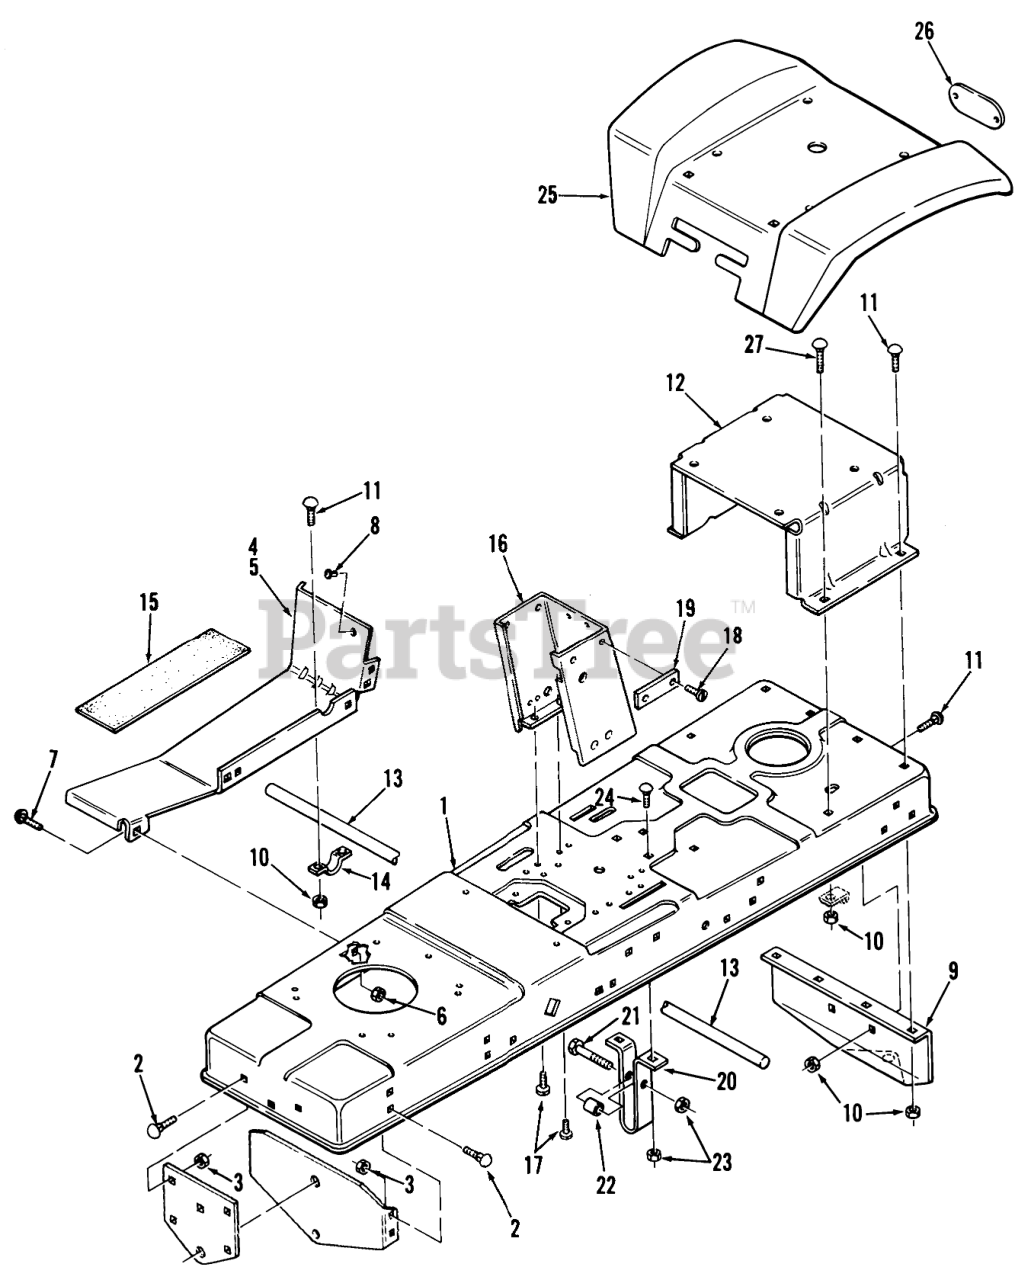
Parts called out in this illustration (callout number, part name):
1	Frame
2	CARRIAGE BOLT -4
3	Nut
4	Footrest RH
6	Nut
7	CARRIAGE BOLT -4
8	BUMPER-RUBBER
9	HITCH-DRAWBAR
10	Nut
11	CARRIAGE BOLT -4
12	Support-Seat
13	SHAFT-REAR
14	CLAMP
15	PAD-FOOTREST
16	Hoodstand
17	SCREW
18	S.T. Screw 5/16-18 X 3/4
19	Spacer
20	Guide-Mower
21	Bolt
22	SPACER
23	Nut
24	Bolt-Carriage
25	Assy-Fender & Plate
26	REFLECTOR-STICK ON
27	Bolt-Carriage
